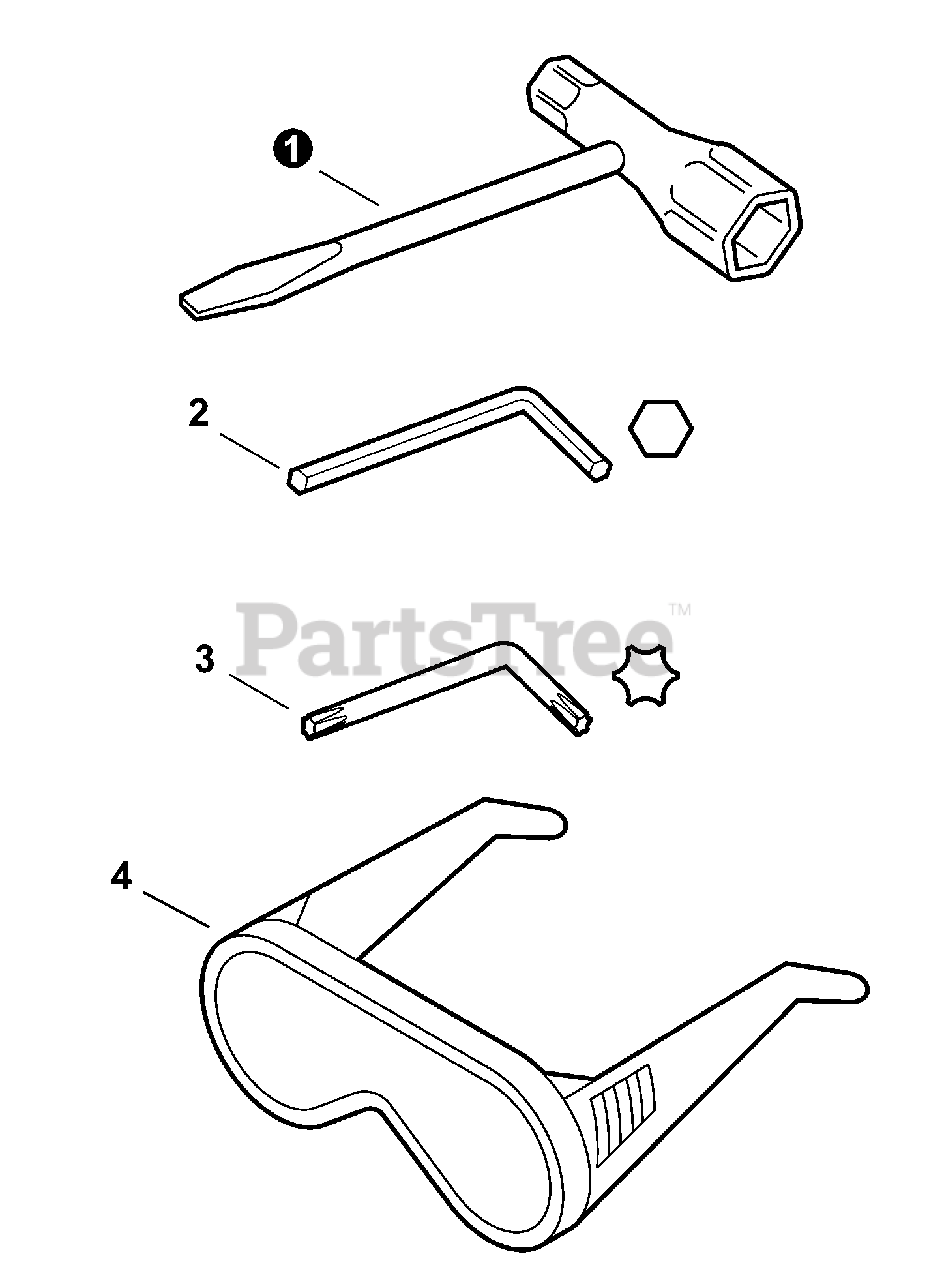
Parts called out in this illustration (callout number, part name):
1	T-WRENCH 10×19mm
2	WRENCH, ALLEN 4MM
3	WRENCH, ALLEN T27 80×30
4	GLASSES, SAFETY
